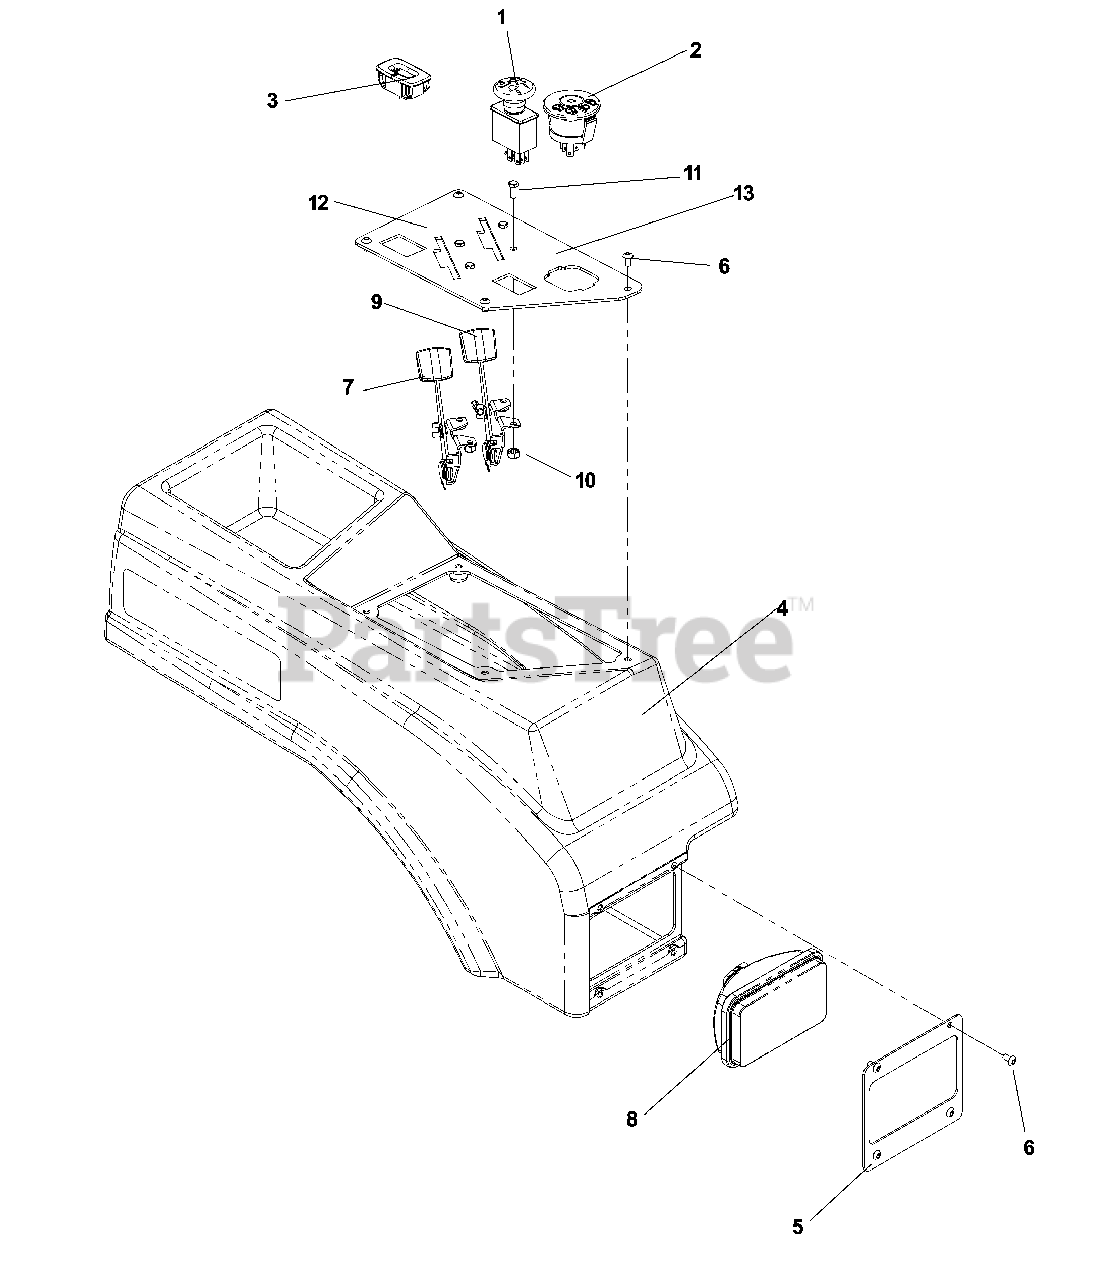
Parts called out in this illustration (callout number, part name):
1	SWITCH, BLADE
2	IGNITION SWITCH
3	HOUR METER
4	TANK, CONSOLE, RT
5	PLATE LIGHT
6	SCR #10-24 X 3/8 SKT HD BLK OX
7	CABLE THROTTLE
8	HEADLIGHT
9	CABLE CHOKE
10	NUT 10-24 NYLOC
11	HCS #10-24 X 1/2
12	CONTROL PANEL
13	DECAL, CONTROL
